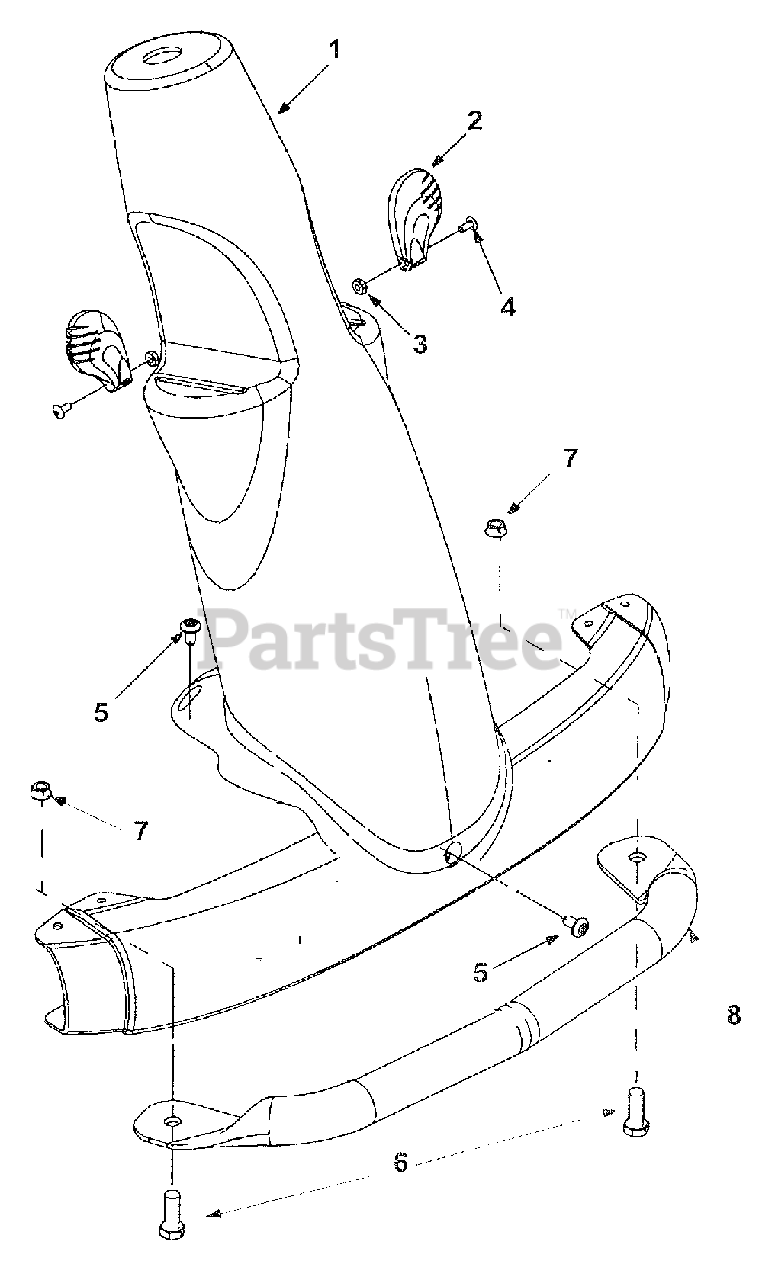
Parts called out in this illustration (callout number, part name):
1	Steering Column: Black
2	Control Knob
3	Hex Nut 8-32
4	Pan Head Machine Screw #8-32
5	Hex Screw TT 1/4-20 x .50"
6	Hex Screw 3/8-16 x 1.0"
7	Lock Nut
8	Bumper Tube: Front, Yellow
